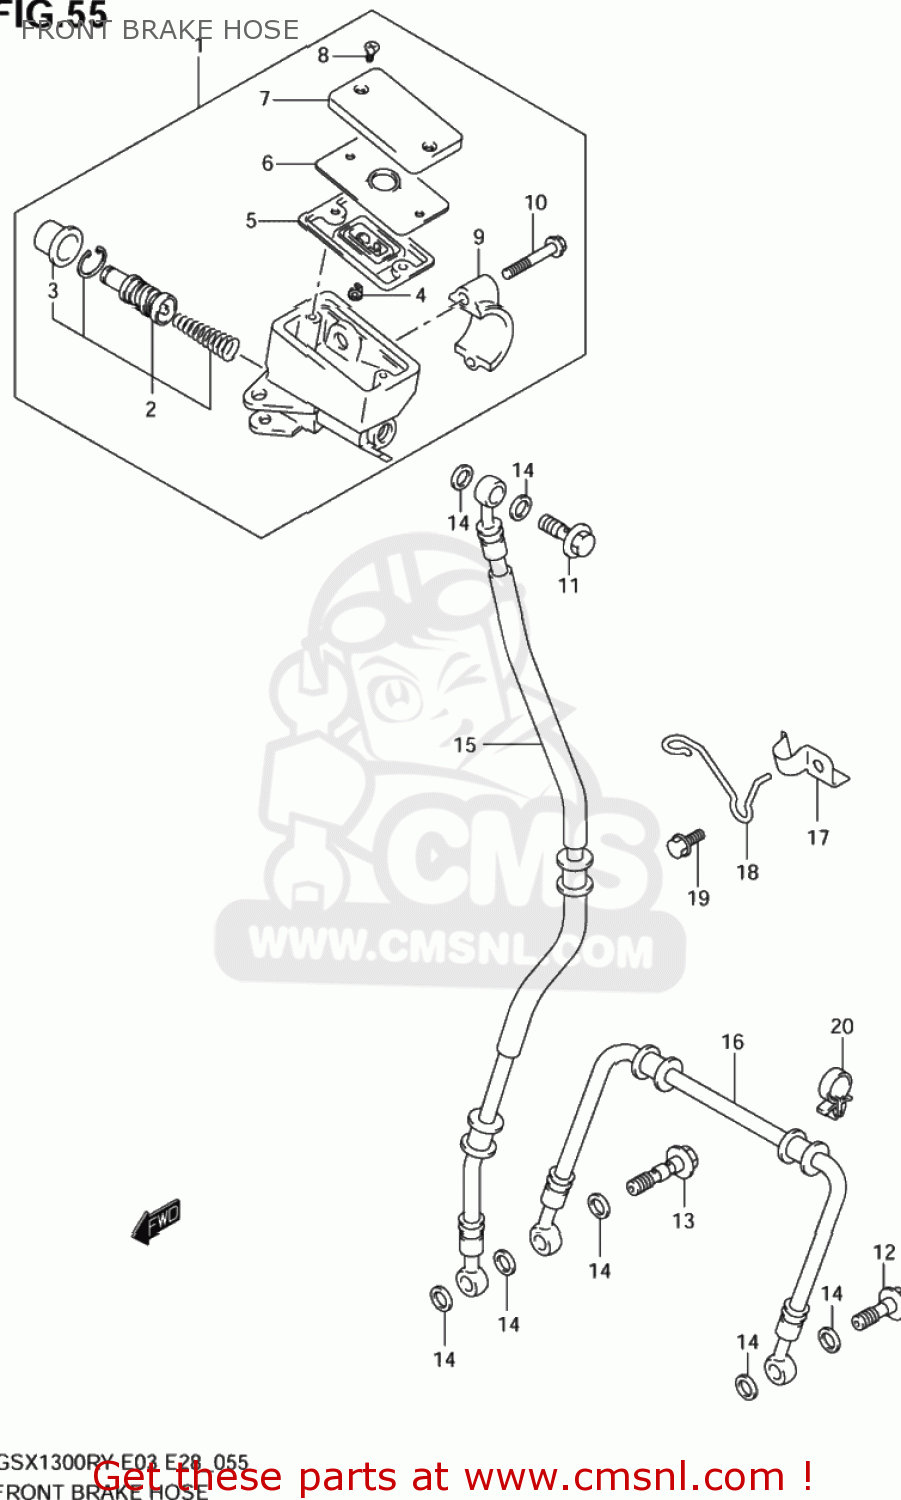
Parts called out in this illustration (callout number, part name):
1	CYLINDER ASSY,FR MASTER
2	PISTON & CUP SET
3	BOOT
4	PROTECTOR
5	6
6	PLATE,DIAPHRAGM
7	CAP
8	SCREW
9	HOLDER
10	BOLT(6X22)
11	BOLT UNION
12	BOLT UNION
13	BOLT UNION
14	WASHER(10X15X1.5)
15	HOSE COMP,FRONT BRAKE
16	HOSE COMP,FRONT BRAKE
17	CLAMP,FR BRAKE HOSE UPR
18	GUIDE,FR BRAKE HOSE NO.1
19	BOLT
20	CLAMP
